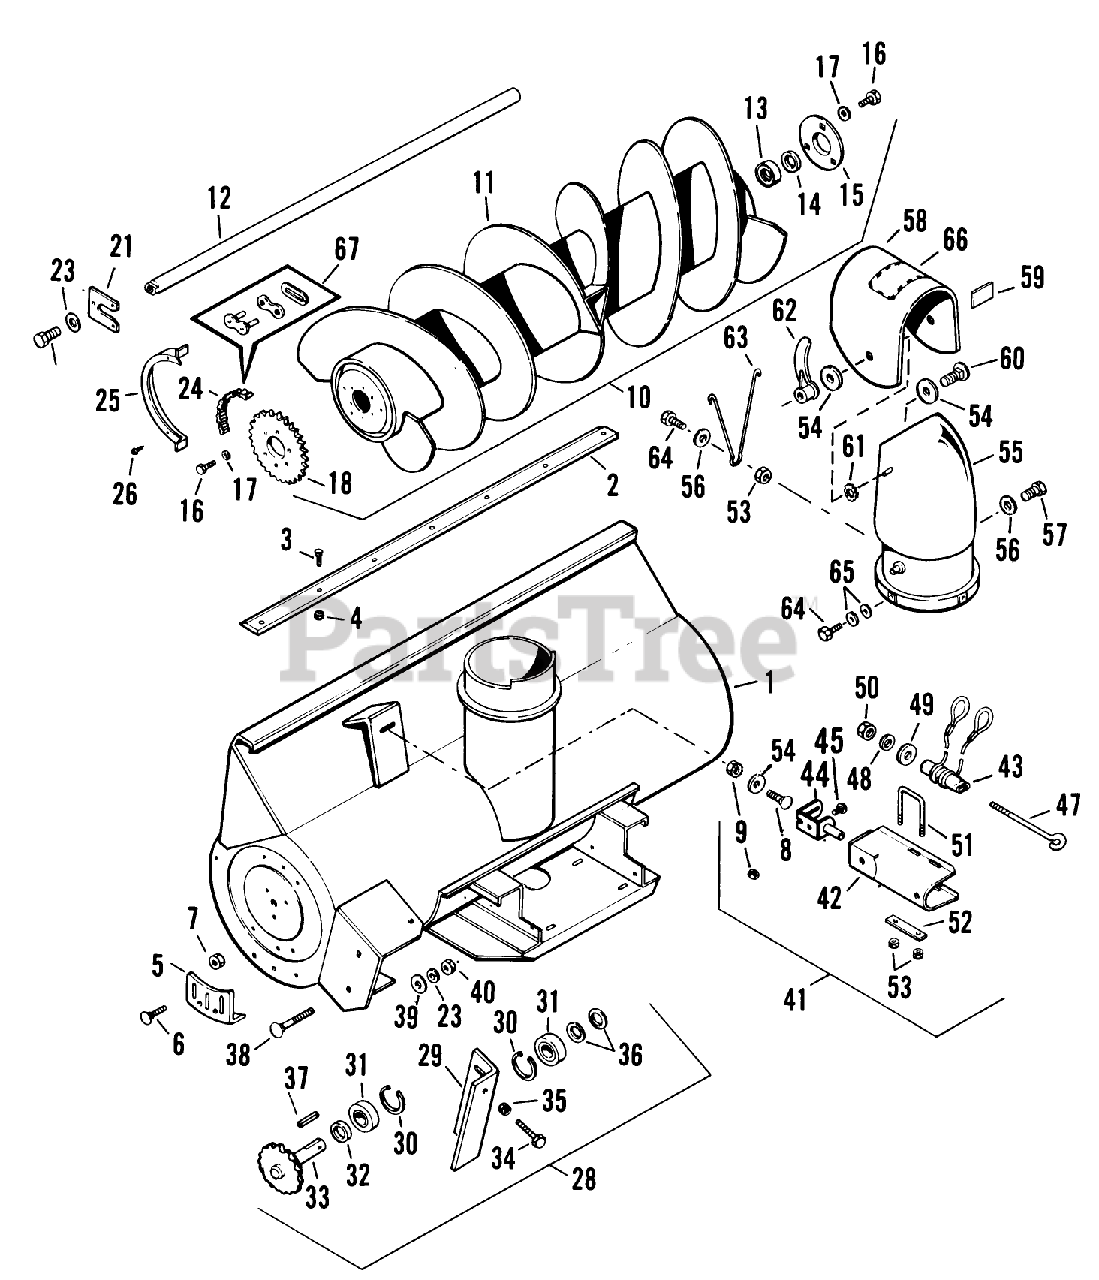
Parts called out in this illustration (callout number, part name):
1	Assembly-Header Housing
2	Blade-Scraper
3	BOLT-BLADE TO HEADER
4	Nut 1/4-20
5	Shoe-Skid
6	Carriage Bolt 5/16-18 x 3/4
7	Keps Nut 5/16-18
8	Bolt
10	Auger Assembly
11	Auger
12	Auger Shaft
13	Bearing
14	Washer
15	Spring
16	Bolt
17	Lockwasher
18	Control Rod-Traction
20	Bolt
21	PLATE AUGER MOUNTING
23	Lockwasher
24	Auger Drive Chain #40
25	Chain Guard
26	SCREW
28	Jackshaft Assembly
28	Jackshaft Housing w/Bearings
29	Jackshaft Housing
30	Ring-Snap
31	BEARING-GEAR BOX
32	Spacer
33	Jackshaft and Sprocket
34	Self Tapping Screw 5/16-18 x 1 3/4
35	Nut
36	WSHR SPROCKET TO BRG
38	Carriage Bolt 1/2-13 x 3 1/2
39	WASHER
40	Eslok Nut
41	Stack Drive Bracket
42	SHROUD-STACK DRIVE
43	Cable Tube and Sleeves
44	Bracket and Tube
45	Bolt-Carriage
46	Lock Nut 5/16-18
47	EYE BOLT DRIVE TUBE
48	Spring Washer
49	Washer
50	Nut
51	U-BOLT
52	Friction Strap
54	WASHER
54	Decal
55	Assy.-Elbow & Pivot
55	Decal
56	Washer
57	Bolt
58	Deflector Elbow
59	MOLDING DEFLECTOR
60	Bolt-Carriage
61	Washer 5/16 (Special Locking)
62	STRAP-LOCKING
63	Spring Hook
64	H H C S
65	Washer
66	Caution Decal
67	Chain Repair Kit
